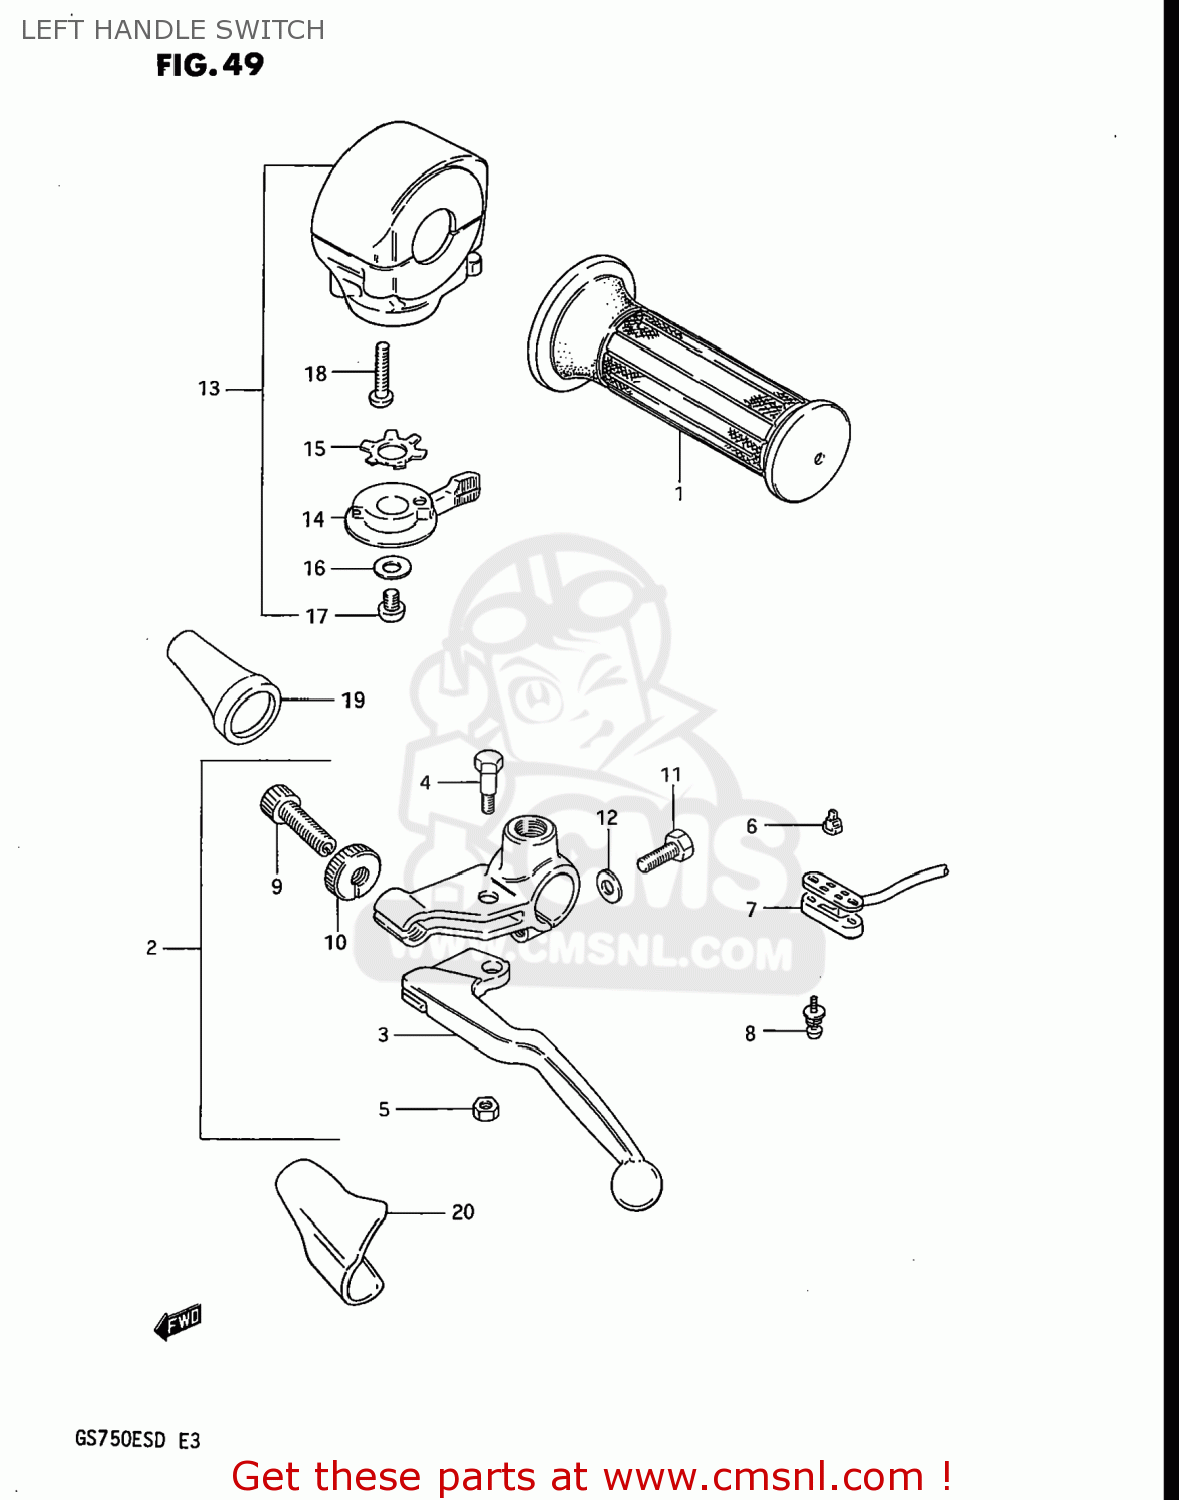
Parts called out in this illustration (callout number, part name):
1	GRIP,L
2	LEVER ASSY,CLUTCH
3	LEVER,CLUTCH
4	BOLT,LEVER PIVOT
5	NUT 6MM
6	CONTACT,SWITCH
7	COVER,FR BK TERMINAL BASE
8	SCREW
9	ADJUSTER,CABLE
10	NUT,CABLE ADJUSTER LOCK
11	BOLT,CLUTCH LEVER HOLDER
12	WASHER
13	SWITCH ASSEMBLY,HANDLE,LEFT
14	LEVER,STARTER
15	WASHER
16	WASHER 6MM
17	SCREW
18	SCREW
19	BOOT,CLUTCH CABLE
20	COVER,CLUTCH LEVER
